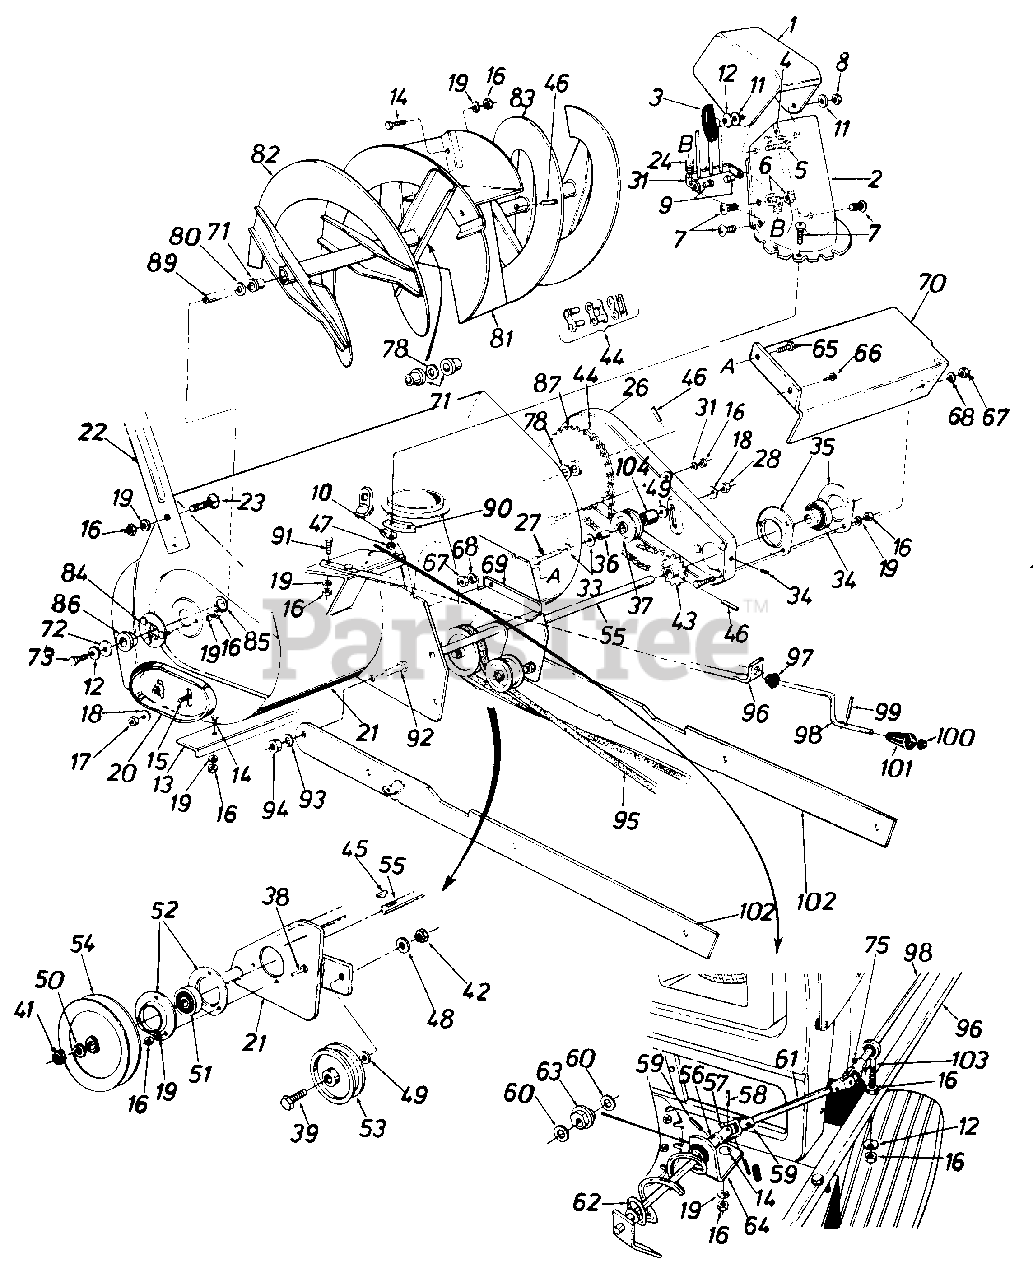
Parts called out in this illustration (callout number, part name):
1	Upper Chute
2	Lower Chute
3	Knob Handle Ass'y.
4	Truss Mach. Scr. 5/16-18 x .75" Lg.
5	Carriage Bolt 5/16-18 x 1.0"
6	Hex Cent. L-Nut 5/16-18 Thd.
7	Truss Mach. Scr. 1/4-20 x .75" Lg.
8	Hex Cent. L-Nut 5/16-18 Thd.
9	Shld. Nut 1/4-20 Thd.
10	Fl.-Wash. 1/4" I.D.
11	Fl.-Wash. .344" I.D. x 1.125"
12	Bell. Wash. .345" I.D. x .88"
14	Carriage Bolt 5/16-18 x .62"
15	Carriage Bolt 3/8-16 x .62"
16	Hex Nut 5/16-18 Thd.
17	Hex Jam Nut 3/8-16 Thd.
18	Bell. Wash. .40 I.D. x .88"
19	L.-Wash. 5/16" I.D.
20	Slide Shoe
21	Spiral Hsg. Ass'y.-36"
22	Guide Blade
23	Carriage Bolt 5/16-18 x .62"
24	Extension Spring
26	Chain Guard Ass'y.
27	Hex Bolt 3/8-16 x 2.00 Lg.*
28	Hex Inst.-Nut 3/8-16 Thd.
33	Fl.-Wash. .385" I.D. x .87" O.D.
34	Ball Brg. .75" I.D.
35	Flangette
36	Spacer .375" I.D. x .60" O.D.
37	Fl.-Idlere w/Flanges 1.875
38	Hex Sems Bolt 5/18 x .75" 4.
39	Hex Bolt 3/8-16 x 1.75" 4.
41	Hex Jam Nut 3/4-10 Thd.
42	Hex Jam Nut 3/8-16 Thd.
43	Sprocket Ass'y.-14 Teeth
44	#420 Chain x 1/2" Pitch- 77 Links
45	#61 Hi-Pro-Key 3/16 x 5/8"
46	Spring Pin Spir. 5/16" Dia. x 1.75" 4.
47	Hex L-Nut 1/4-20 Thd.
48	L.-Wash. 3/8" I.D.
49	Fl.-Wash. .406" I.D. x 1.25"
50	Spring L.-Wash. 3/4" I.D.
51	Self-Aligning Brg.
52	Flangette
53	Ider Pulley
54	5/8 V-Pulley .75" I.D. x 6"
55	Drive Shatt Ass'y.
56	Joint Brkt. Ass'y.
57	Joint Block
58	Oval Head Rivet
59	Spiral Pin 1/8" Dia.
60	Fl.-Wash. .385" I.D. x .62"
61	Chute Crank Ext. Rod
62	Chute Crank Ass'y. R.H.
63	Plastic Bushing .380" I.D.
64	Chute Crank Brkt.
65	Hex Bolt 1/4-20 x .62" Lg.
66	Hex Wash. S-Tap Scr. 1/4-20 x .50" 4
67	Hex Nut 1/4-20 Thd.
68	L.-Wash. 1/4" I.D.
69	Belt Cover
70	Drive Shaft Cover
71	Plastic Bushing
72	Washer .39" I.D. x 1.75" O.D.
73	Hex Bolt 5/16-18 x .88" Spec.
75	Cotter Pin 3/32" Dia.
78	Fl.-Wash. 1.03" I.D. x 1.62"
80	Fl.-Wash. 1.0" x 1.75"
85	Snap Ring for 1.50" Shaft
86	Flange Brg. w/flats 1.00" I.D.
87	Sprocket Hub Ass'y. 40 Teeth
89	Spiral Axle
90	Chute Flange Keeper
91	Hex Bolt 5/16-18 x 1.5" 4.
92	Hex Bolt 1/2-13 x 1.25" 4.
93	L.-Wash. 1/2" I.D.
94	Hex Nut 1/2-13 Thd.
95	"V"-Belt
98	Chute Crank 34.5" 4.
99	Roll Pin .12 Dia. x .63
100	Push Nut 3/8" Rod
101	Knob Black
102	Linkage Arm
103	Eye Bolt 5/16-18 x 3.0" 4.
104	Idler Spacer
